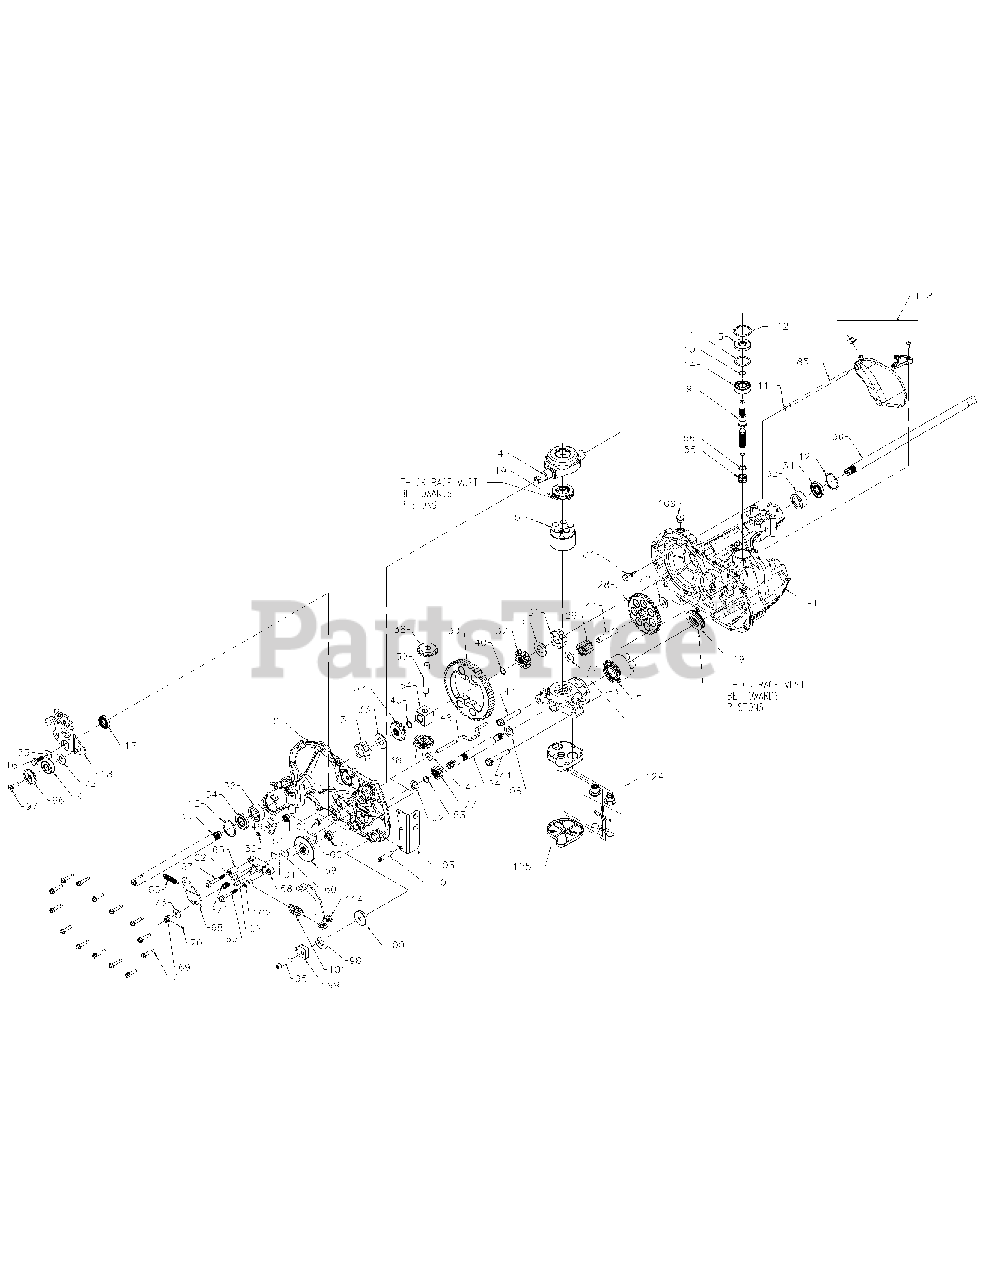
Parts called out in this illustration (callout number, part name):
1	Main Housing, Assembly
2	Side Housing, Assembly
3	Center Section, Assembly
4	Swashplate, Trunnion Machined
5	Block - Assembly
7	Hex Flange Screw 1/4-20 X 1.25
9	Shaft, Input
10	Ring, Retaining
12	Ring, Retaining
13	Seal, Lip .67 X 1.58 X .276
14	Ball, Bearing 17mm ID X 40mm OD X12mm
16	Bolt, Hex Flange Head 5/16-24 X .94 (Patch)
17	Lip Seal 18 X 32 X 7
18	Arm, Control
19	Bearing, 30 X 52 X 13 Thrust
24	Shaft, Motor
27	Gear - Pinion, 12T
28	10T/49T Gear
29	Gear, LDT Jackshaft
30	60T Bull Gear
31	Sleeve Bushing, Inboard
32	Sleeve Bushing .75 x 1.575 x .625
33	Washer, 3/4 X 1 1/2 X .13 THK
34	Lip Seal Axle Seal
35	Shaft, Axle (R.H.) DD
36	Shaft, Axle (L.H.) DD
37	Miter Gear 12T (Splined)
38	Miter Gear 12T
40	Ring, Spiral Retaining
41	Pin, Jackshaft
42	Magnet, Ring
44	Bolt, Hex Flange 3/8-24 X 2.5
48	Rod, Bypass Actuator
49	Arm, Bypass
50	Retaining Ring, 250 External
51	Seal, Lip .741 X .250 X 250 TC
52	Flat Washer, 5/9 ID X 1.0 OD X .05THK
53	Retaining Ring
54	Bearing, Center Block
55	Spring - Helical Compression
58	Brake, Yoke Kit
59	Rotor, Brake
60	Brake, Puck
61	Puck Plate
62	Brake Actuating Pin
63	HFHCS 1/4-20 X 2 w/Patch SPECIAL FLANGE
66	Spring, Brake ARM BIAS
68	Arm, Brake
69	Slotted Hex Nut, 5/16-24
70	Cotter Pin, 3/32 X 3/4
71	Compression Spring Anti-Drag
73	Flat, Washer 11/32 I.D. X 7/9 O.D
74	Seal, Kit
84	Fitting, 5/16 SAE 5/32 Tube
85	Hose, Expansion Tank
94	Bearing, Ball .62 ID X 1.39 .44
95	Screw, Socket Head Cap 5/16-24 X 1 1/2
96	Spacer, Locating
97	Screw, SFHCS 5/16-18 X 1
98	Arm, Return
99	Puck, Adjusting
100	Washer, Flat
101	Spring, Extension
102	Spacer, .260 ID X .560 OD X .870
103	Bracket, Torque
108	Washer, Motor Shaft .71 ID X 1.15 OD X .030 THK
110	Screw, Torx Head 5/16-18 T.F.
111	O-Ring .103 X .299 ID
114	Spring, Guide
124	Center Section - Filter - Bypass Assembly
125	Filter Assembly
128	Kit, Expansion Tank
